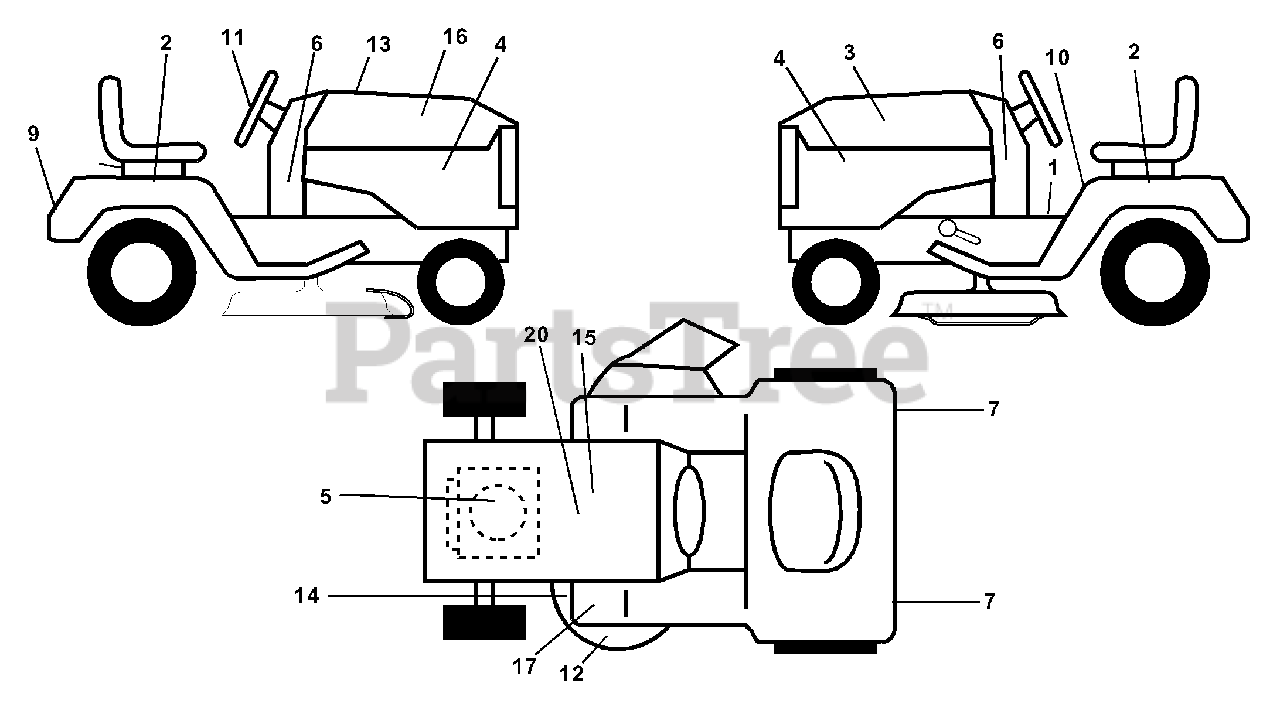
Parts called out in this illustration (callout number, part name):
2	Decal Fender Auto
3	Decal Hood LH
4	Decal Side Panel
5	Decal HP Engine
7	Reflector Tail Light
9	Decal Fender Logo
10	Decal Fender Danger E
11	Decal Ins Strg Whl
12	Decal Deck Mulch/Vented
13	Decal Replacement Hood
14	Decal V-Belt Schematic
15	Decal Battery Power Pro
16	Decal Hood Rh
17	Decal Clutch/Bake
20	Decal Bat Dan/Psn
